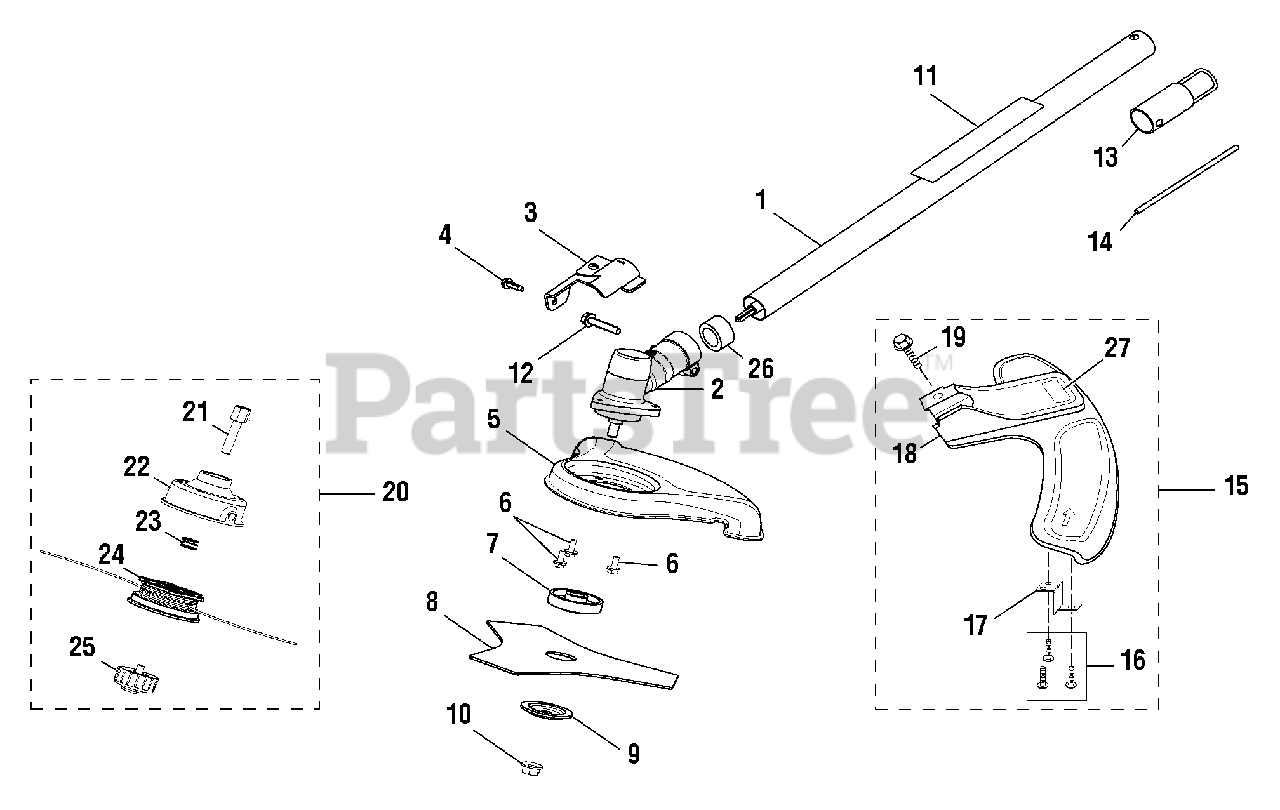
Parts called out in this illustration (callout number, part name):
1	STRAIGHT SHAFT ASSEMBLY
2	GEAR CASE ASSEMBLY
3	GRASS DEFLECTOR CLAMP
4	SCREW (#10-24 X 5/8 in. HEX WASHER HD.)
5	BLADE GUARD
6	SCREW (#10-24 X 1/2 in. SEMS SLOTTED HEX HD.)
7	FLANGED WASHER
8	BLADE (TRI-ARC(TM))
9	CUPPED WASHER
10	BLADE NUT, LEFT-HANDED THREADS
11	WARNING LABEL
13	HANGER CAP
14	HEAD LOCKING TOOL
15	GRASS DEFLECTOR ASSEMBLY
17	LINE CUTTING BLADE
18	GRASS DEFLECTOR
19	SCREW (#1/4-20 X 1-1/4 in. HEX WASHER HD.)
20	TRIMMER HEAD ASSEMBLY
21	TRIMMER HEAD SHAFT ADAPTOR
22	TRIMMER HEAD
23	COMPRESSION SPRING
24	SPOOL WITH LINE (.095)
25	RETAINING CAP, LEFT-HANDED THREAD
26	SPACER
27	GRASS DEFLECTOR LABEL
